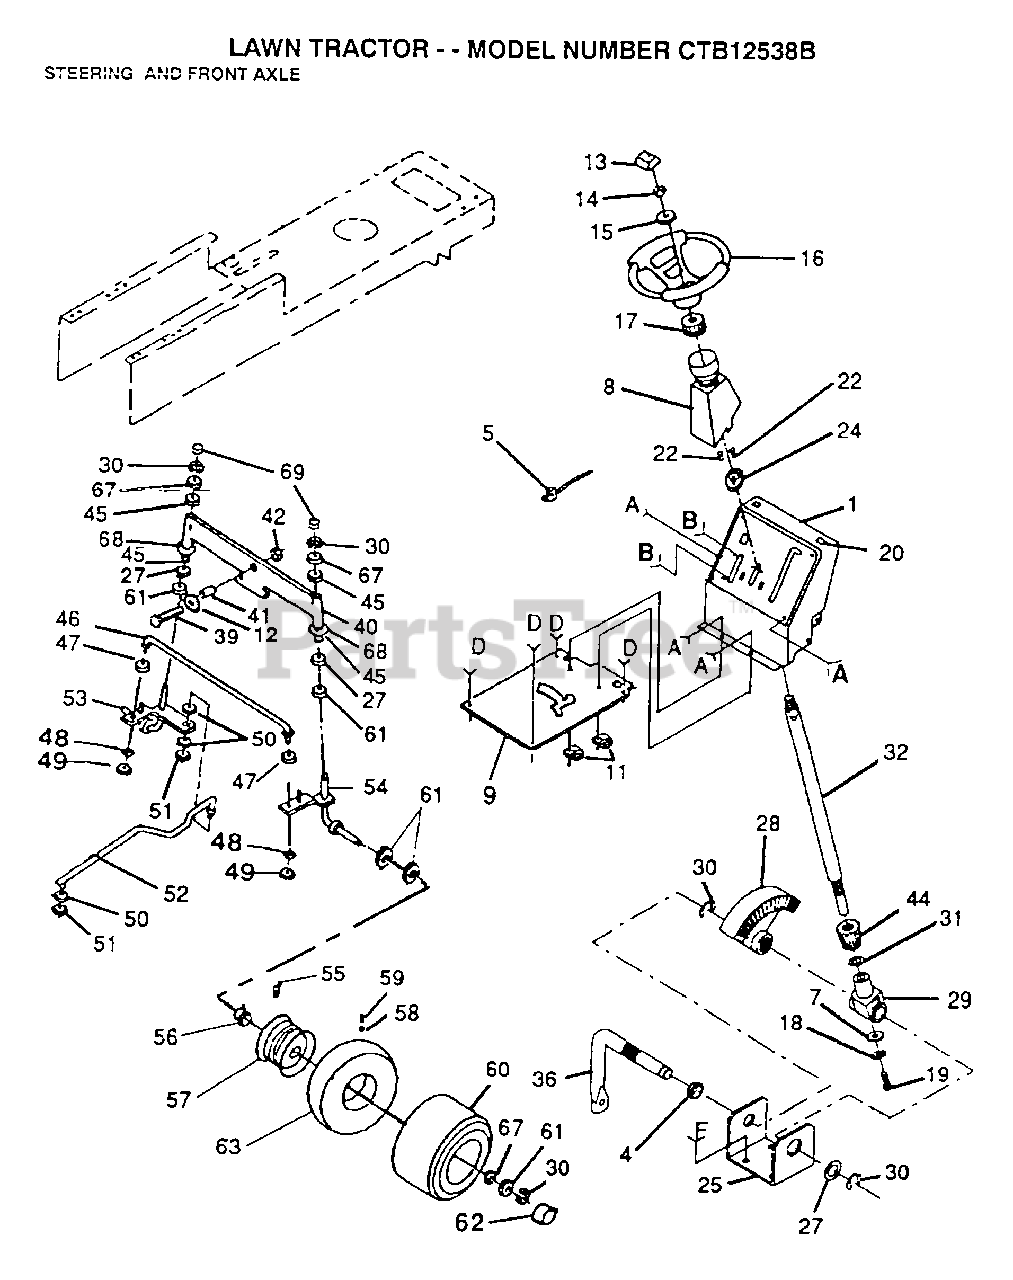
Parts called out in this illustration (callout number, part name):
4	NYLINER T
8	"TUBE, STR SHAFT"
11	CLIP T
13	INSERT-WHEEL LT
15	WASHER
17	ADAPTER LT
18	LOCKWASHER
19	"SCREW,SPECIAL"
24	"BUSHING,STEERING"
25	"BRKT,STEERING"
27	WASHER .T
29	SUPPORT.SHAFT
30	RING
31	THRUST WASHER
39	BOLT LT
41	BEARING
44	"GEAR,PINION"
45	COL. SRTG. BEAR.
46	ROD TIE
47	WASHER M
48	LOCKWASHER
49	NUT.LOCK.5/16-24
50	LOCKWASHER
53	SPINDLE-LH LT
55	FITTING LT
56	"FLANGE, BEARING"
58	VALVE CAP
59	VALVE STEM LT
61	WASHER
62	HUB CAP
63	TUBE.5.3/4.5/6
67	WASHER
68	WASHER
69	CAP
